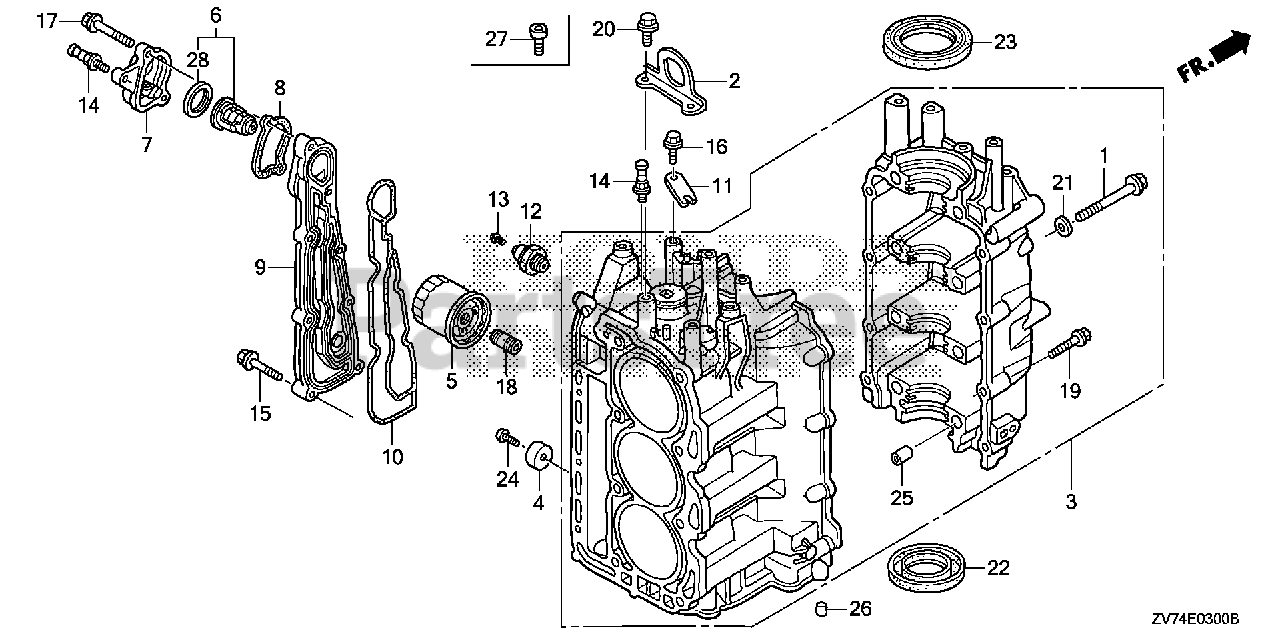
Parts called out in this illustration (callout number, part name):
1	BOLT, FLANGE (8X85)
2	HANGER, ENGINE
3	BLOCK ASSY., CYLINDER *NH8* (DARK GRAY)
4	METAL, ANODE
5	FILTER, OIL (DENSO)
5	FILTER, OIL (TOYO ROKI)
6	THERMOSTAT ASSY.
7	COVER, THERMOSTAT
8	GASKET, THERMOSTAT COVER
9	COVER, WATER JACKET *NH8* (DARK GRAY)
10	GASKET, WATER JACKET COVER
11	PLATE, SHIFT SHAFT
12	SWITCH ASSY., OIL PRESSURE
13	SCREW-WASHER (4X8)
14	BOLT, TIMING BELT ADJUSTING SPRING
15	BOLT, FLANGE (6X22) (CT200)
16	BOLT, FLANGE (6X12) (CT200)
17	BOLT, FLANGE (6X35) (CT200)
18	HOLDER, OIL FILTER
19	BOLT, FLANGE (6X40)
20	BOLT, FLANGE (8X18)
21	WASHER, PLAIN (8MM)
22	OIL SEAL (35X52X8)
23	OIL SEAL (44.5X60.5X8) (NOK)
24	SCREW, PAN (6X18)
25	PIN, DOWEL (10X12)
26	PIN, DOWEL (6X10)
28	RUBBER, RING
